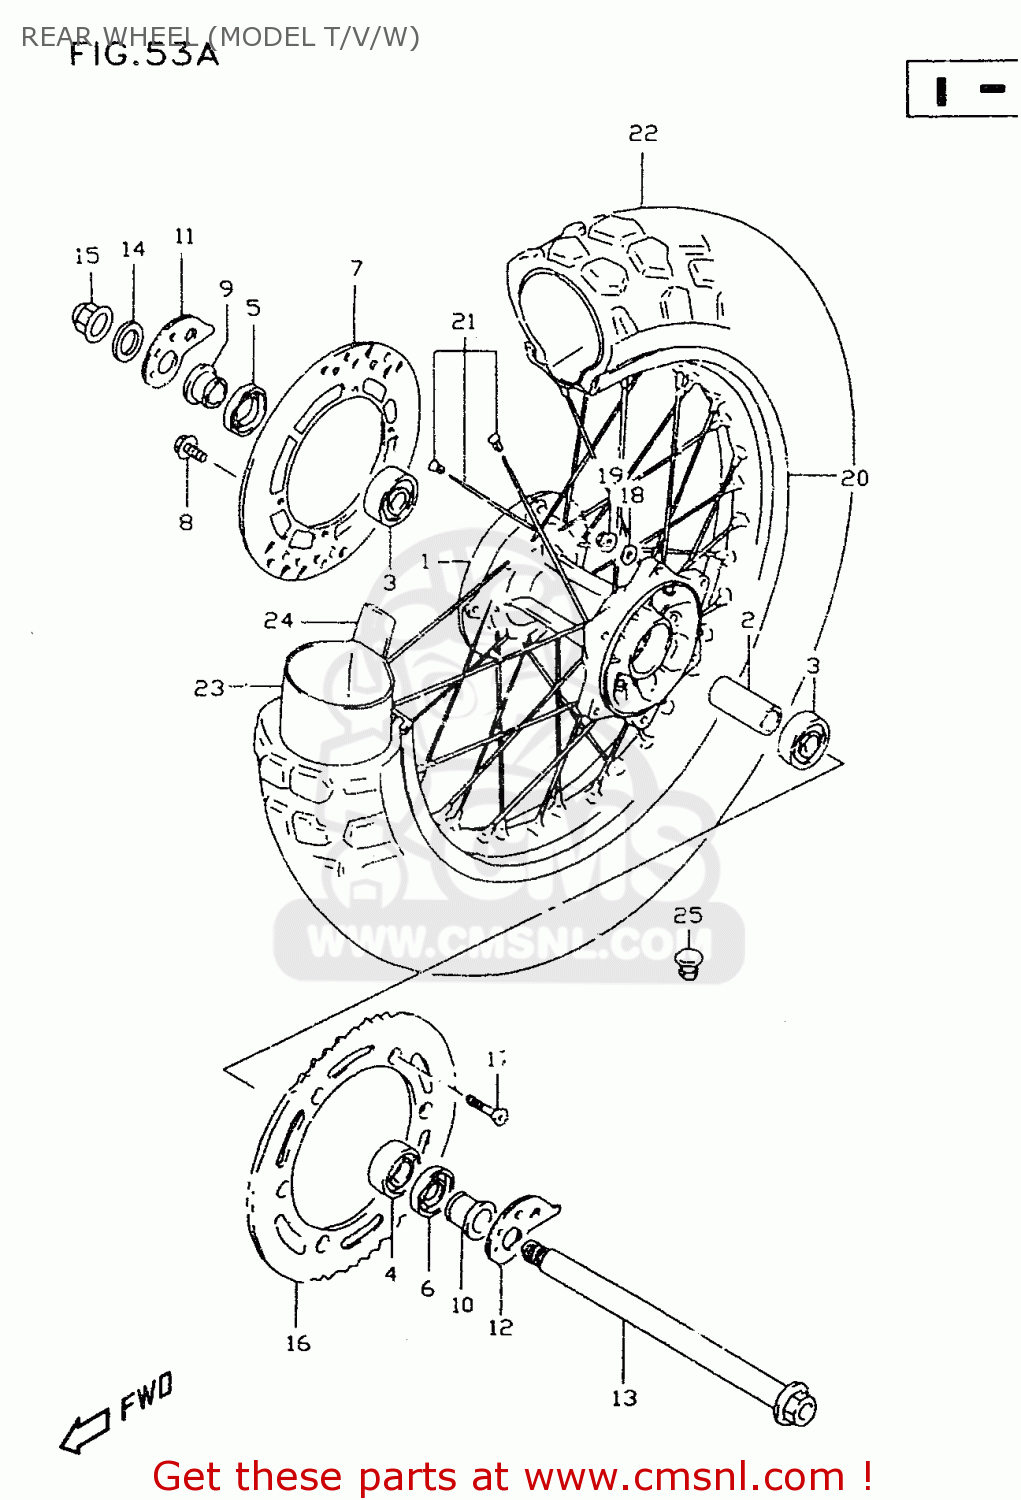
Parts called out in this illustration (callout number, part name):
1	HUB,RR WHEEL
2	SPACER,RR HUB BEARING
3	BALL BEARING
4	BEARING
5	SEAL,OIL(26X42X8)
6	SEAL,OIL(26X47X5)
7	DISC,RR BRAKE
8	BOLT,BRAKE DISC
9	SPACER,RR AXLE,R
10	SPACER,RR AXLE,L
11	ADJUSTER,CHAIN,R
12	ADJUSTER,CHAIN,L
13	AXLE,RR
14	WASHER(19X32X3.2)
15	NUT 18MM
16	SPROCKET,RR(NT:41)
17	SCREW(8X33.5)
18	WASHER
19	NUT
20	RIM,REAR WHEEL (2.15X18)
21	SPOKE SET,RR WHEEL
22	TIRE,REAR 110/90-18
23	TUBE ASSEMBLY,WHEEL,INNER
24	PROTECTOR,WHL INR TUBE
25	CAP(OD:12)
